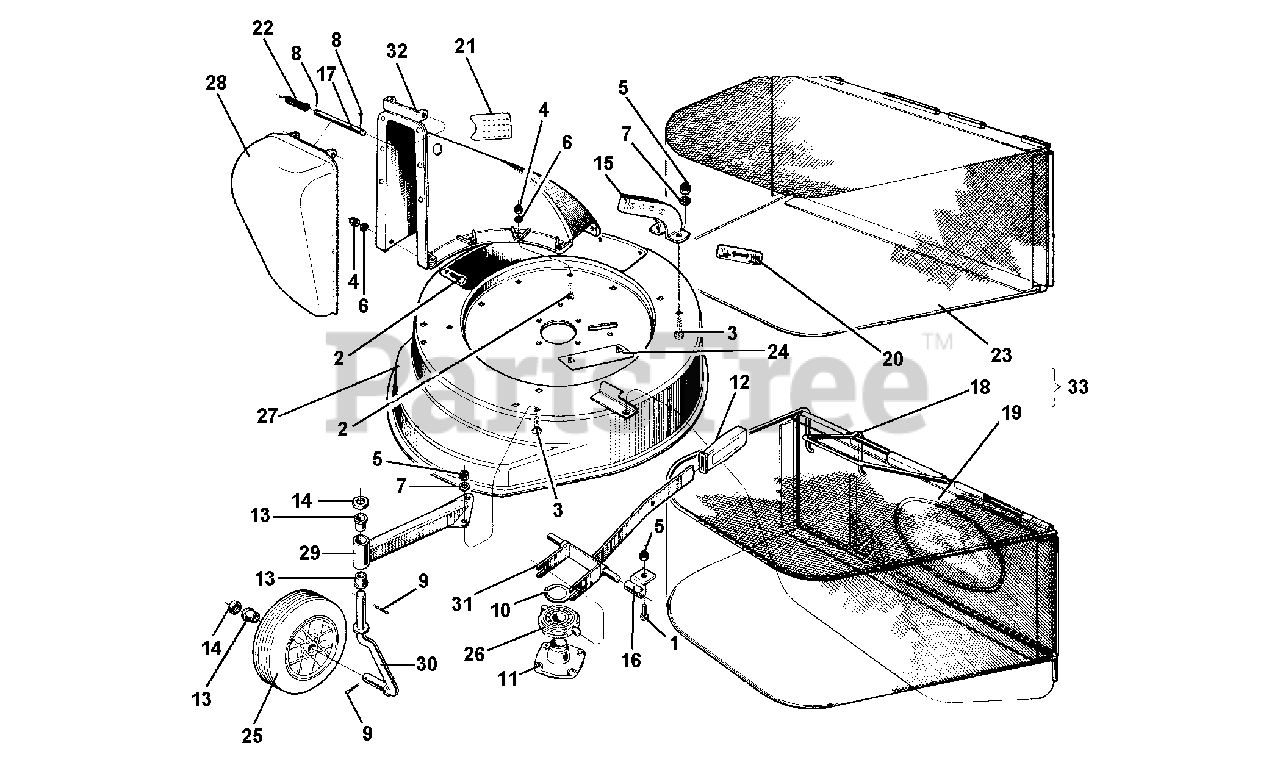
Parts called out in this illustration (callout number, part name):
1	SCREW M8 X 16
2	SCREW M6 X 20
3	SCREW TTQ M8 X 20 UNI 5731
4	NUT, SELF LOCKING M6
5	NUT, SELF LOCKING M8
6	WASHER, FLAT 6.4
7	WASHER, LOCK 8.4
8	COTTER PIN A 3 X 15 UNI 1336 AC.
9	PIN, COTTER 4 X 25
10	EXT. CIRCLIP D 35
11	BLADE HOLDER HUB
15	CUTTING HEIGHT SELECTOR
20	TRANSFER FOR LAWN MOWER
22	DEFLECTOR SPRING
25	SMALL WHEEL
27	LAWN MOWER CRANKCASE
29	WHEEL SUPPORT
31	ADJUSTING LEVER
33	CATCHER COMPLETE
